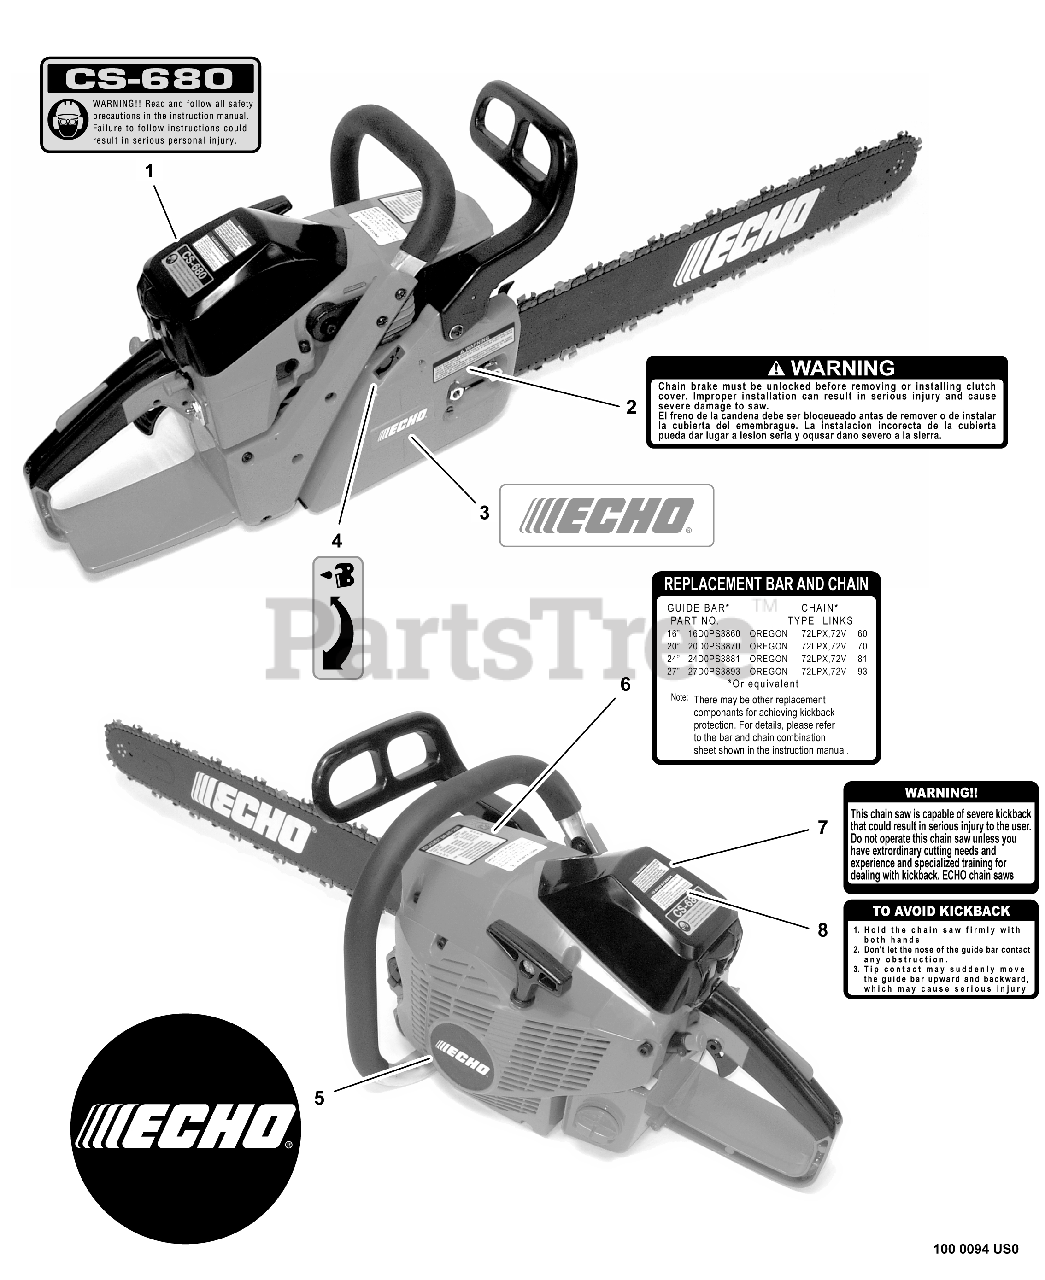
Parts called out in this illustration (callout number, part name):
1	LABEL - MODEL CS-680
2	LABEL - WARNING
3	LABEL - ECHO
4	LABEL - CAUTION
5	LABEL - NOISE
6	LABEL - ECHO
7	LABEL - BAR & CHAIN
8	LABEL - KICK BACK
9	LABEL - KICK BACK
10	LABEL - ATTENTION
